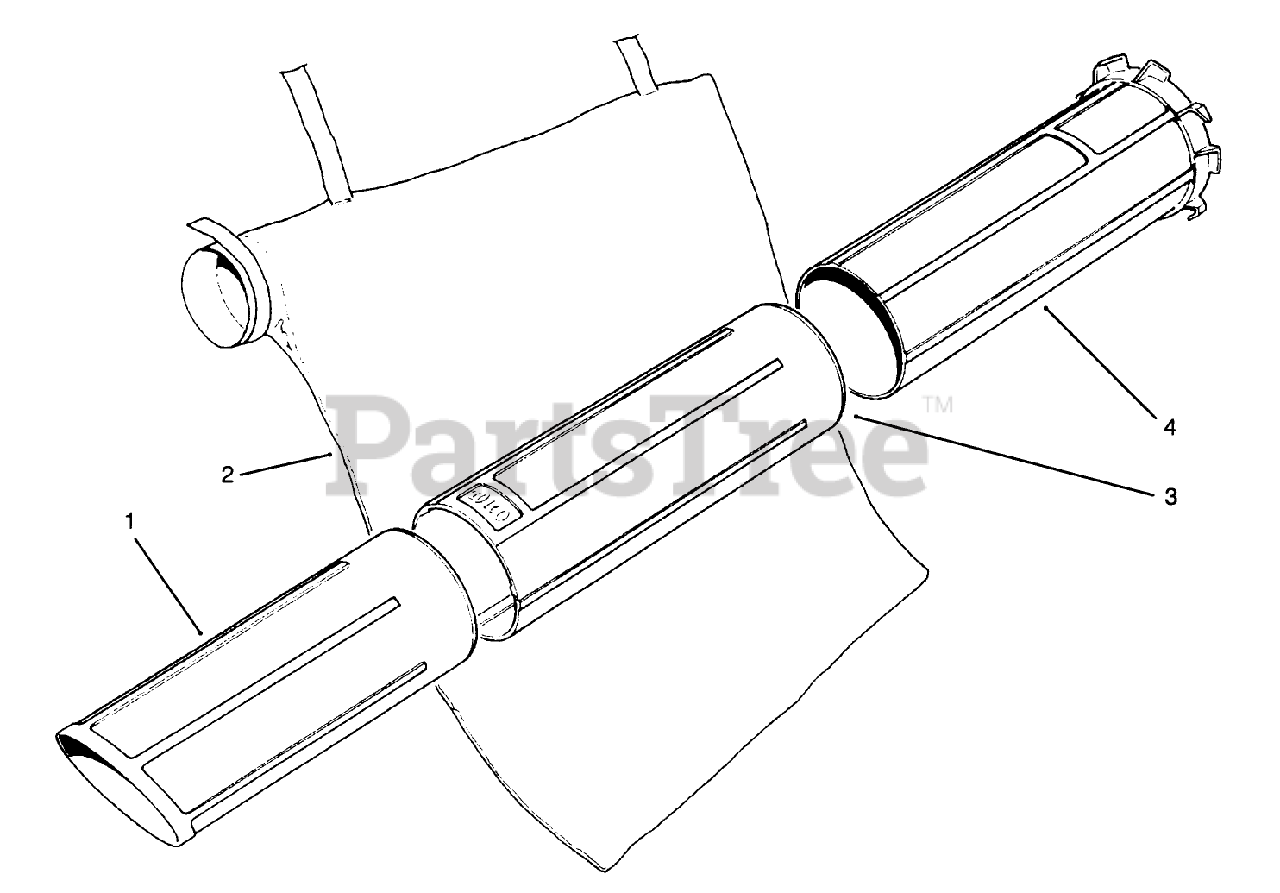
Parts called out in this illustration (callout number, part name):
1	LOWER VAC TUBE
2	VACUUM BAG
3	MIDDLE VAC TUBE
4	UPPER VAC TUBE
